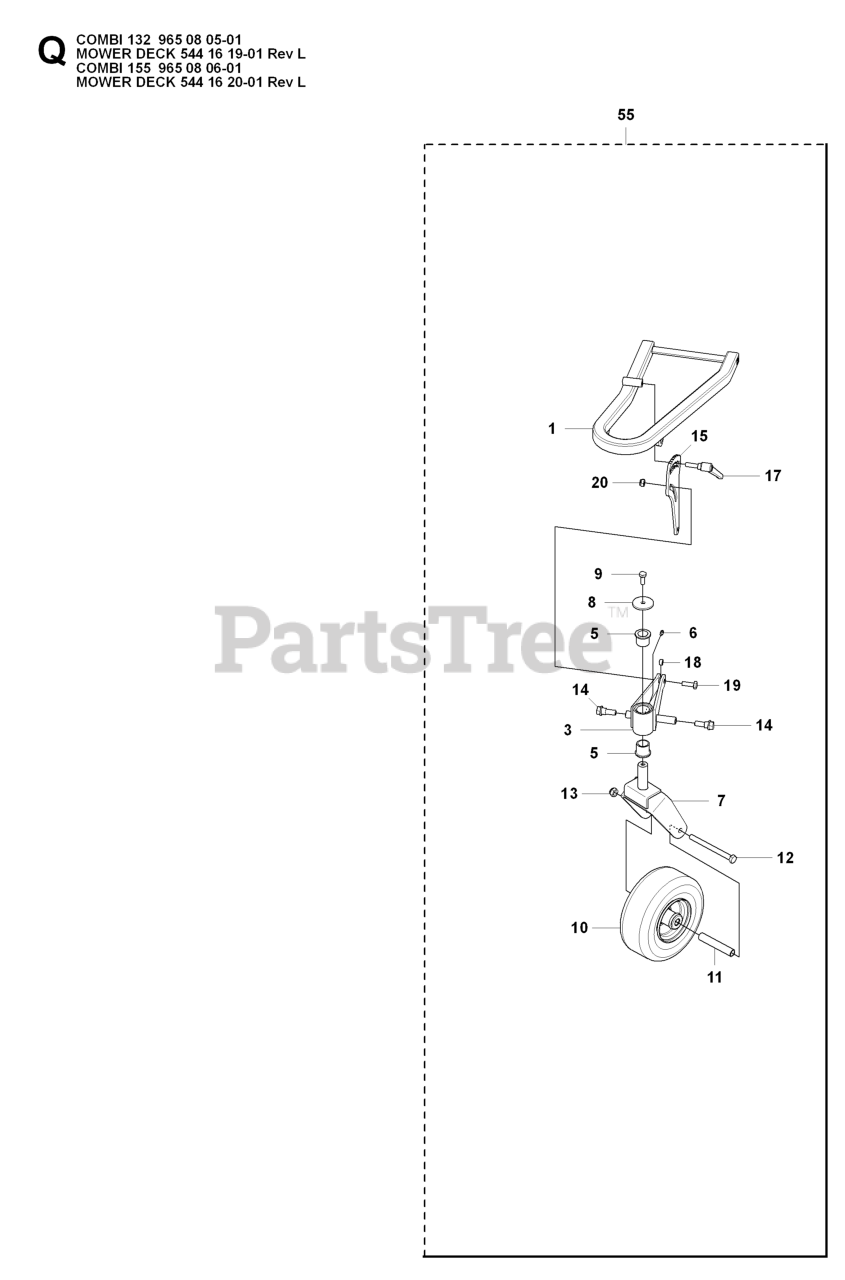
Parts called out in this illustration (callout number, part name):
1	SUPPORTING ARM LEFT
3	PIVOT WHEEL SUPPORT LEFT
6	GREASE NIPPLE
7	FORK PIVOT WHEEL
10	TIRE/WHEEL.CASTER.9X3.5-4.SMOO
15	SHEET HEIGHT ADJUSTER
17	TURNING KNOB M 10
18	SLEEVE PIVOT WHEEL SUPPORT
20	NUT
55	WHEEL SUSPENSION LEFT
